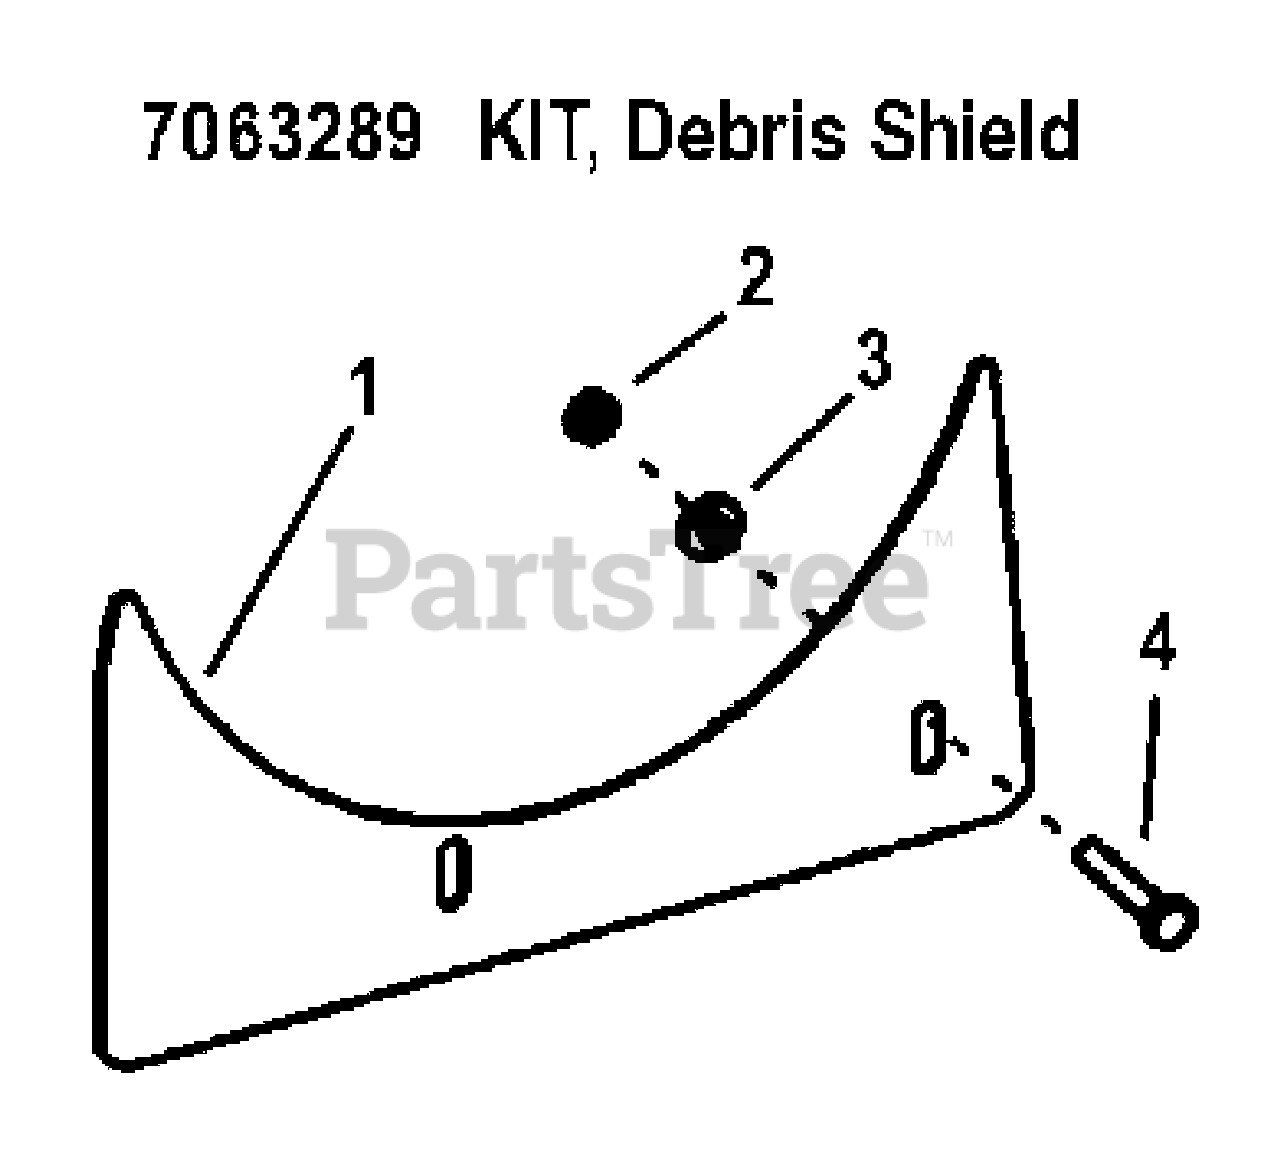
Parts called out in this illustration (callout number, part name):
1	SHIELD, GRASSCATCHER (R/B 7063289)
2	NUT, HTL, 1/4C GR.B YZ
3	WASHER, FLAT .28X.63X.065 YZ
4	HHCS, 1/4C X1-1/2 GR5 BZ
